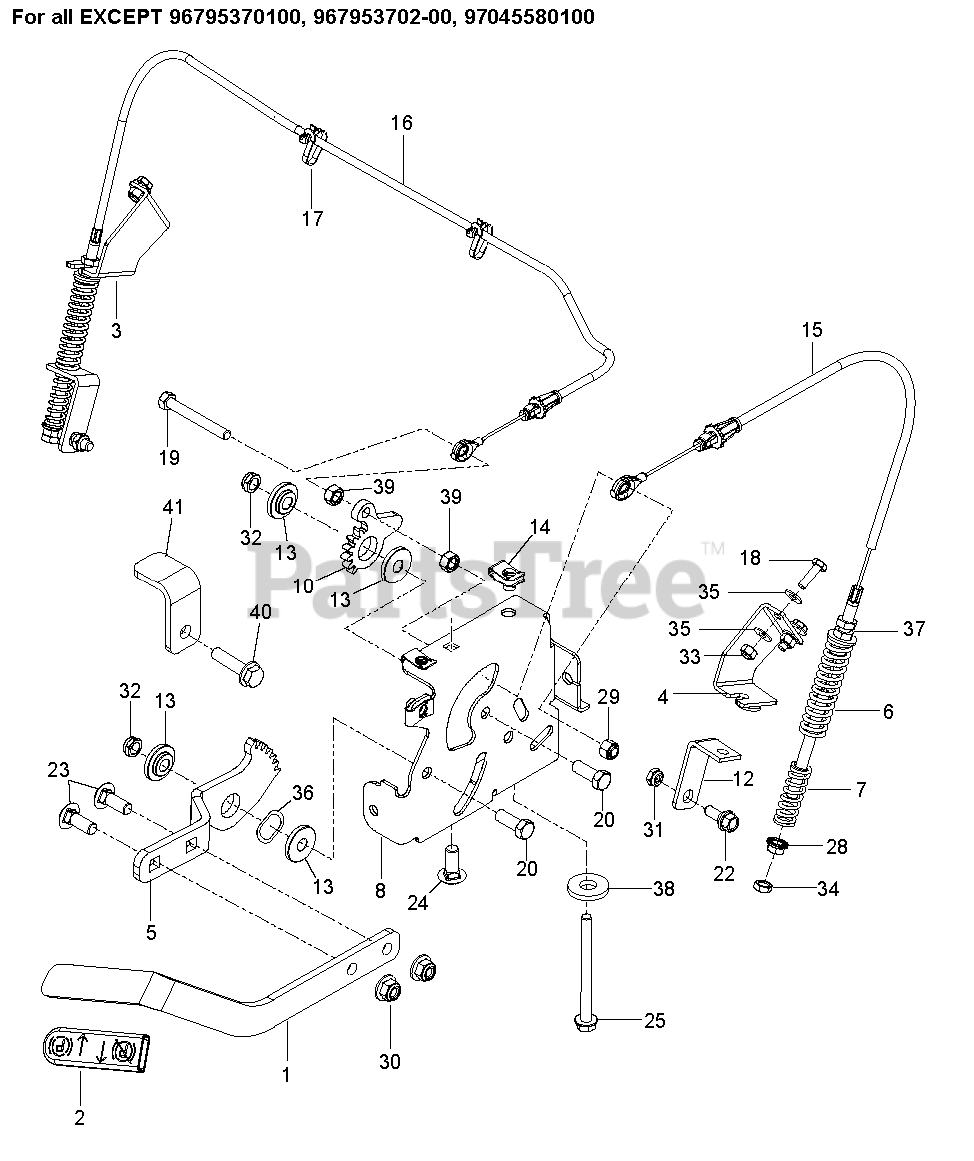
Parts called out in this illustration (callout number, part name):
1	ARM BRAKE BLACK MS-431
2	GRIP, PARK BRAKE
3	BRACKET BRAKE, RT BLACK MS-431
4	BRACKET BRAKE, LT BLACK MS-431
5	GEAR.INPUT.PARKING.BRAKE.MZ
6	SPRING, RETURN
7	SPRING, ENGAGEMENT
8	MOUNT.PNT.BRAKE.MZ.EDIP
10	GEAR OUTPUT;PARKING BRAKE;STAN
12	BRKT, BRAKE, BLK
13	BUSHING, BRAKE
14	U-CLIP 5/16-18 NUT RETAINER
15	CABLE.ASSY.BRAKE.CABLE.SHORT
16	CABLE.ASSY.BRAKE.CABLE.LONG
17	TIE WRAP, 8-3/8", W/CLIP
18	HCS 1/4-20X7/8 GR5
19	HCS 5/16-18 X 2 1/2 TPBLT
20	HCS 3/8-16X1.GRD.5.ZD
22	BOLT, SHOULDER
23	RHSNB 3/8C X 1
24	BOLT 5/16C X 3/4" CARRIAGE
25	HHFS 5/16-18 X 3 3/4
28	NUT 5/16C WHIZ
29	NUT 5/16 NYLOC
30	NUT 3/8-16 HEX FLG NYLOC ZD
31	5/16-18 THIN PROF NY
32	NUT HEX 3/8-16 NYLON, THIN
33	NUT.1/4-20.HEX.NYLOC.ZD
34	NUT 5/16-18 HEX JAM ZD
35	WASHER 1/4 SAE
36	WASHER, .825 X 1.087, WAVE
37	WASHER 3/8 SAE FLAT
38	WASHER.9/16 X 1 3/8 X 12 GA.
39	NUT 5/16C HEX
40	HHFS 5/16-18 X 1.25 TPBLT GD 5
41	BRACKET.PNT.LIMIT.ARM.BRK.EDIP
